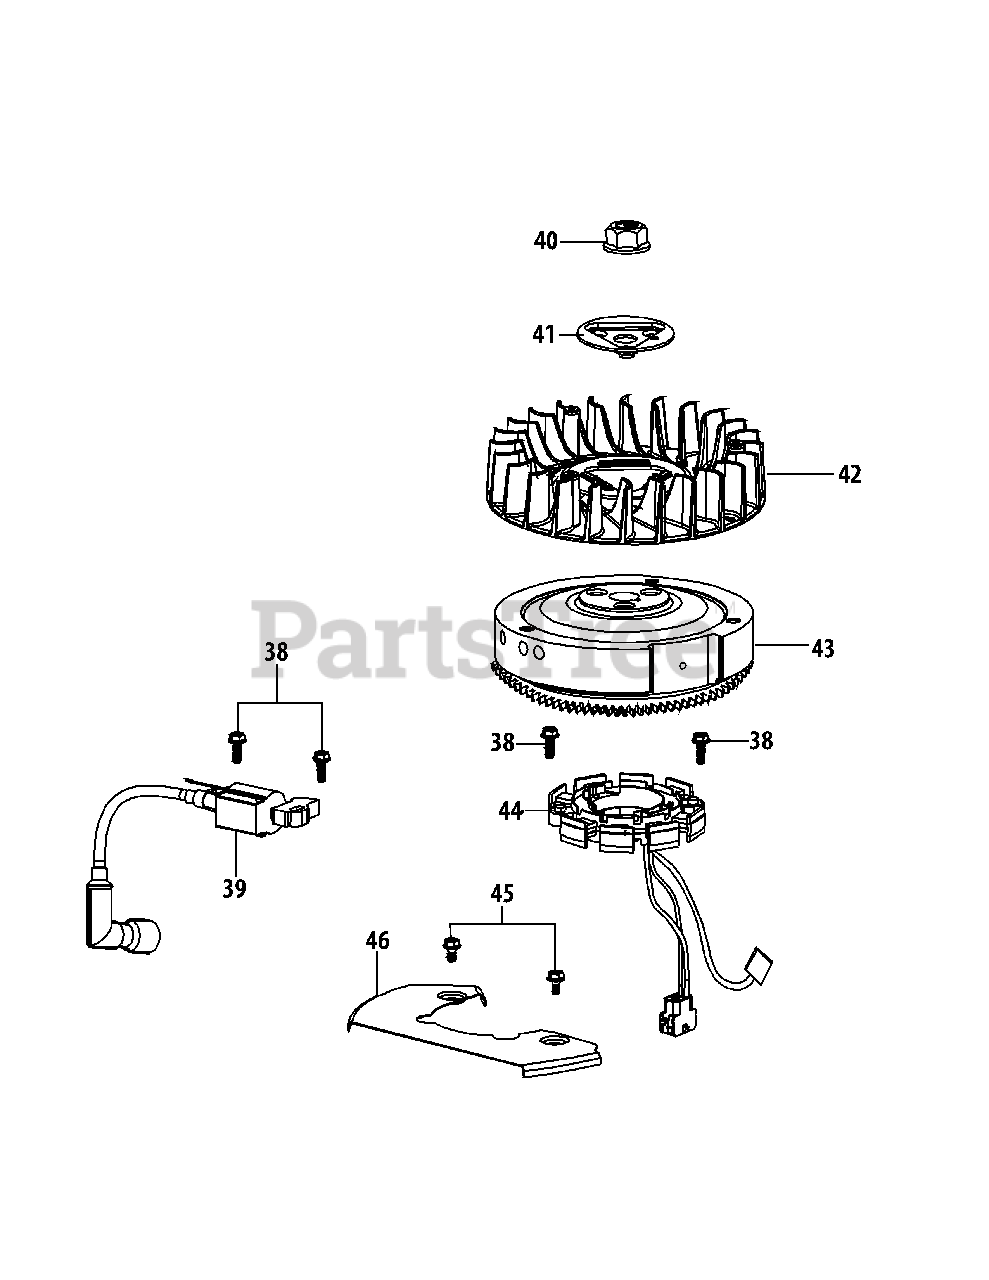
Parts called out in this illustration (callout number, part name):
38	Bolt M6×28
39	Ignition Coil Assembly
40	Flywheel Nut M16×1.5
42	Cooling Fan
44	Coil Assy.Charge
45	Bolt M6×10
